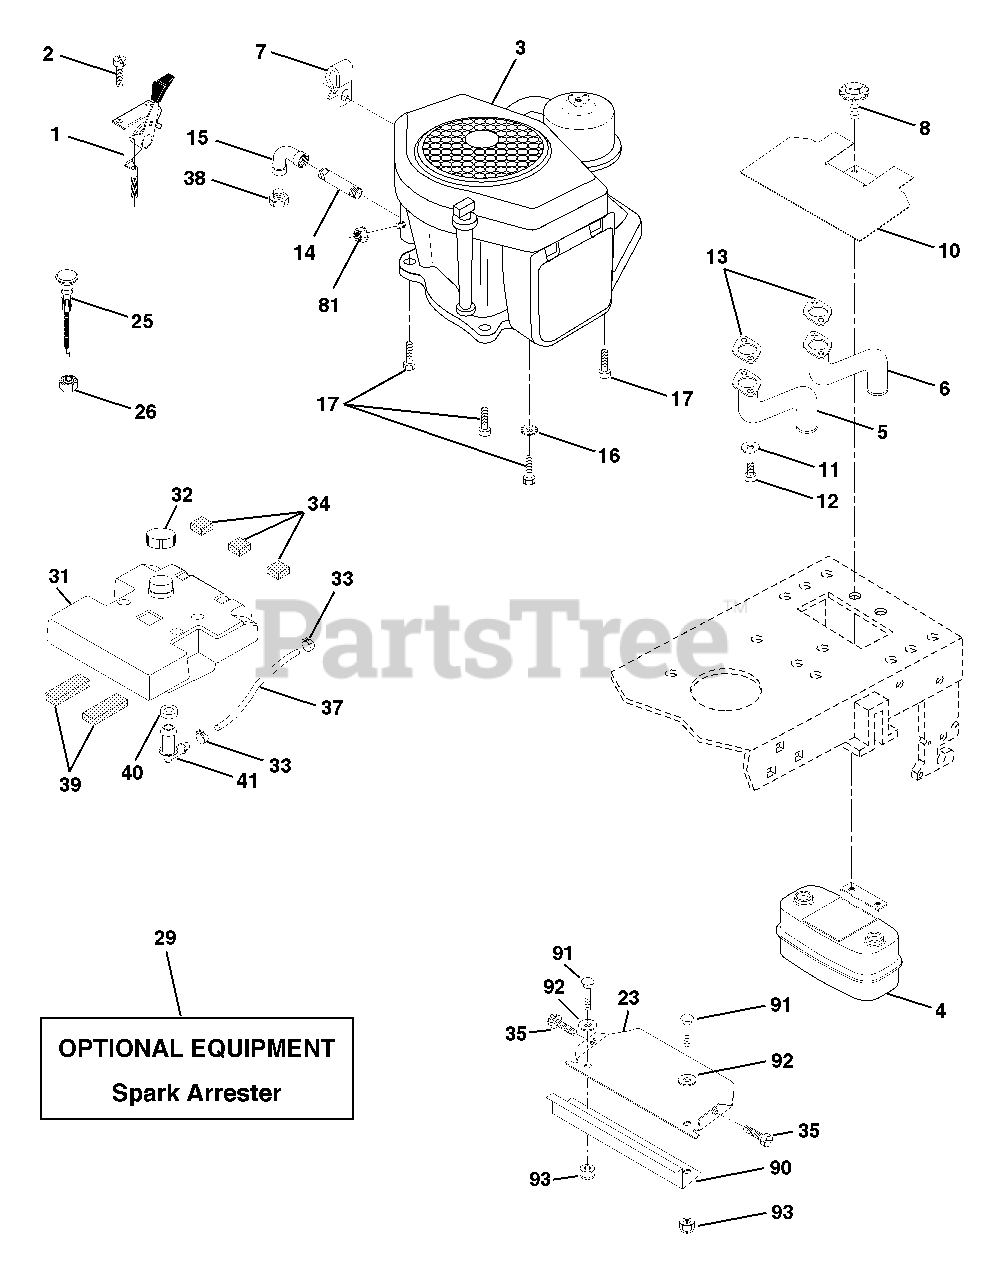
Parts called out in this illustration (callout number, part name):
1	Control Throt Flg 180 LH
2	Screw Hex Thd Cut 1/4-20x5/8 T
4	Muffler Asm Twin Lo-Tone
5	Pipe Exhaust CV18/20 LH
6	Pipe Exhaust CV18/20 RH
7	Clip, Fuel Line
8	Bolt 5/16-18unc x 3/4 W/Sems
10	Shield Heat Muffler CV18/20
13	Muffler Gasket
14	Nipple Pipe 3/8 Npt X 4-1/2"
15	Elbow Std 90 Degree 3/8-18 Npt
16	Washer Lock Ext Tooth 3/8
17	Screw Thdrol 3/8-16 x 1-1/2
23	Shield Browning
25	Choke Control 37"
26	Nut, Keps 3/8-24 Unf
29	Kit Spark Arrestor (Flat Scrn)
31	Tank Fuel 3 50 Rear
32	Cap Asm Fuel Top N/Lany Vented
33	Clamp Hose Blk
34	Pad, Spacer
35	Screw Thdrol 5/16-18 x 3/4
37	Line Fuel 7.5
38	Plug Oil Drain
39	Pad, Idler
40	Bushing
41	Stem Tank Fuel
81	Nut Flange 1/4-20 Starter Nut
90	Guard Debris 97
91	Bolt Blk Fin Hex 1/4-20 unc x 1/2
92	Washer 9/32 x 5/8 x 16 Ga.
93	Nut Lock 1/4 Lge Flg Gr 5 Ainc
